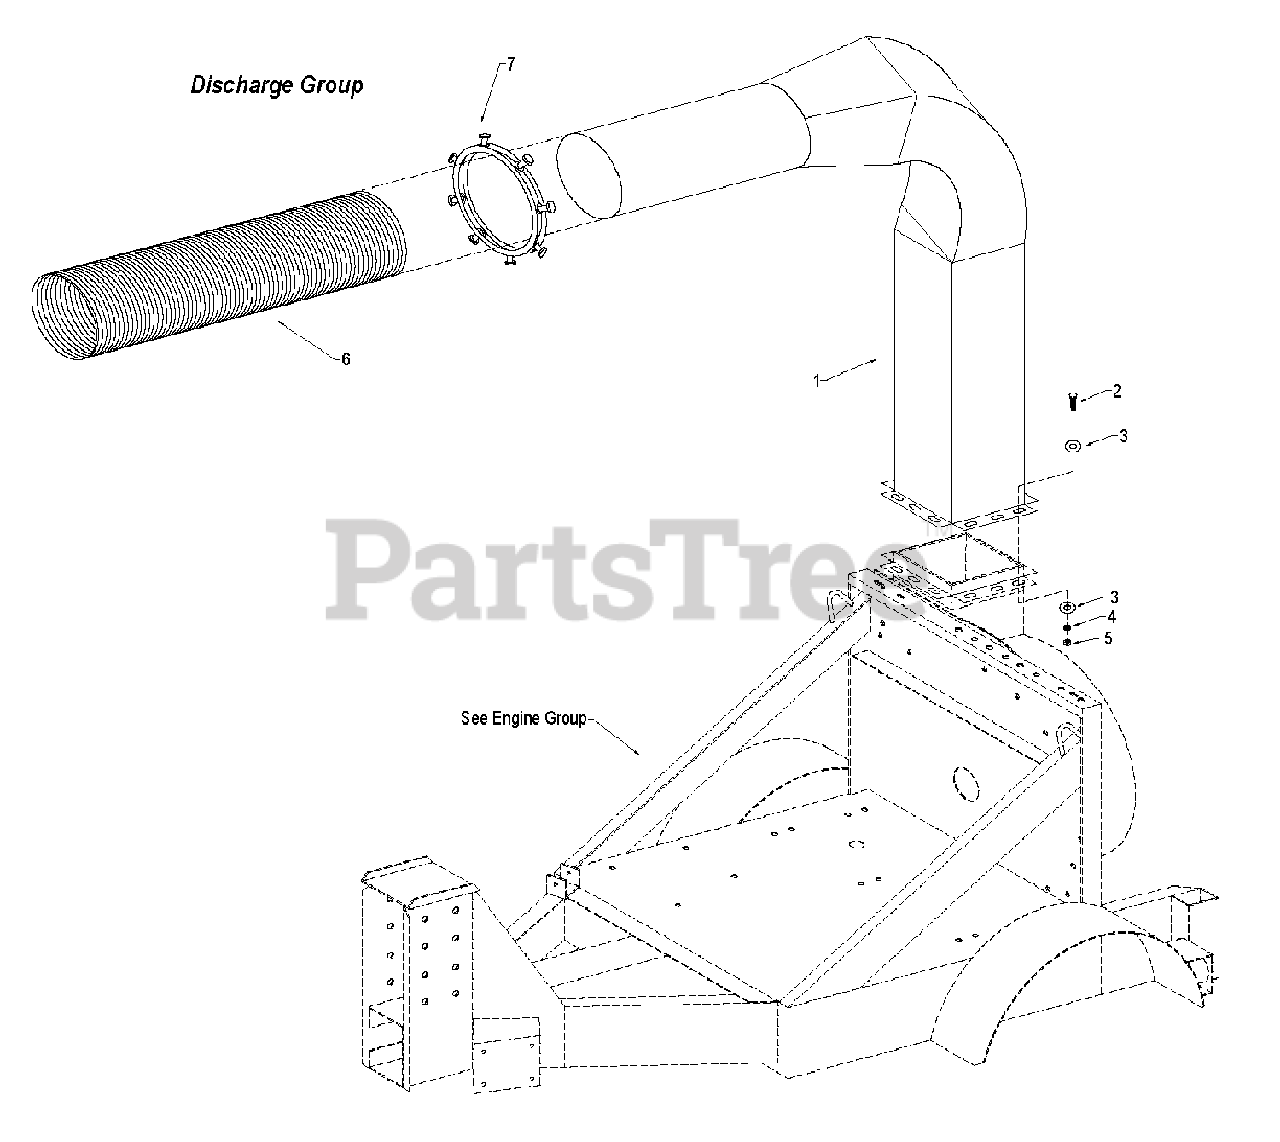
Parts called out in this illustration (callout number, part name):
1	Stack and elbow assy
2	Bolt, hex - 1/2-13 x 1-3/4"
3	Washer, flat - 1/2
4	Washer, lock - 1/2"
5	Nut, hex - 1/2-13
6	Hose, discharge - 12" x 6' metal
7	Ring, squeeze - 12"
